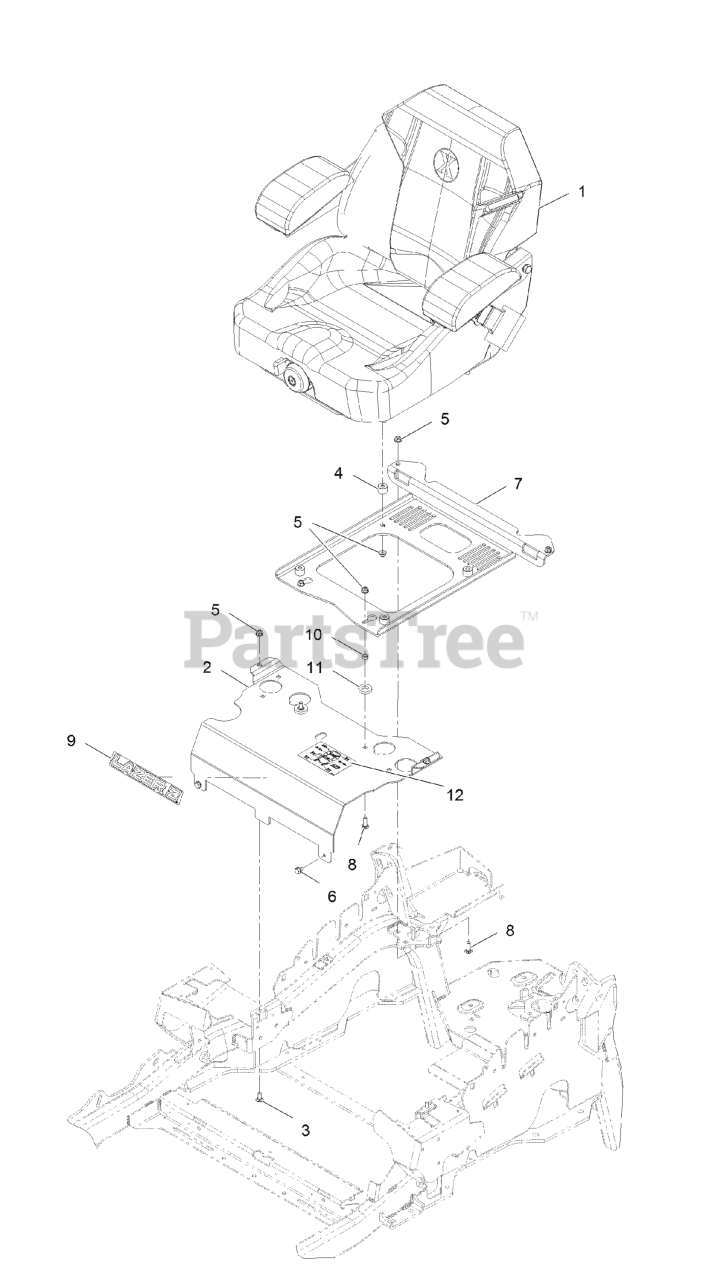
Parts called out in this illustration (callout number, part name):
1	KIT-SUSPENSION SEAT
2	Panel-Front, Seat Mount
3	SCREW-CARR
5	NUT-HF, NI
7	PLATE-SUPPORT, SEAT
8	SCREW-CARR
9	DECAL, LAZER MODEL
10	NUT-HEX
12	DECAL-SERVICE AID
